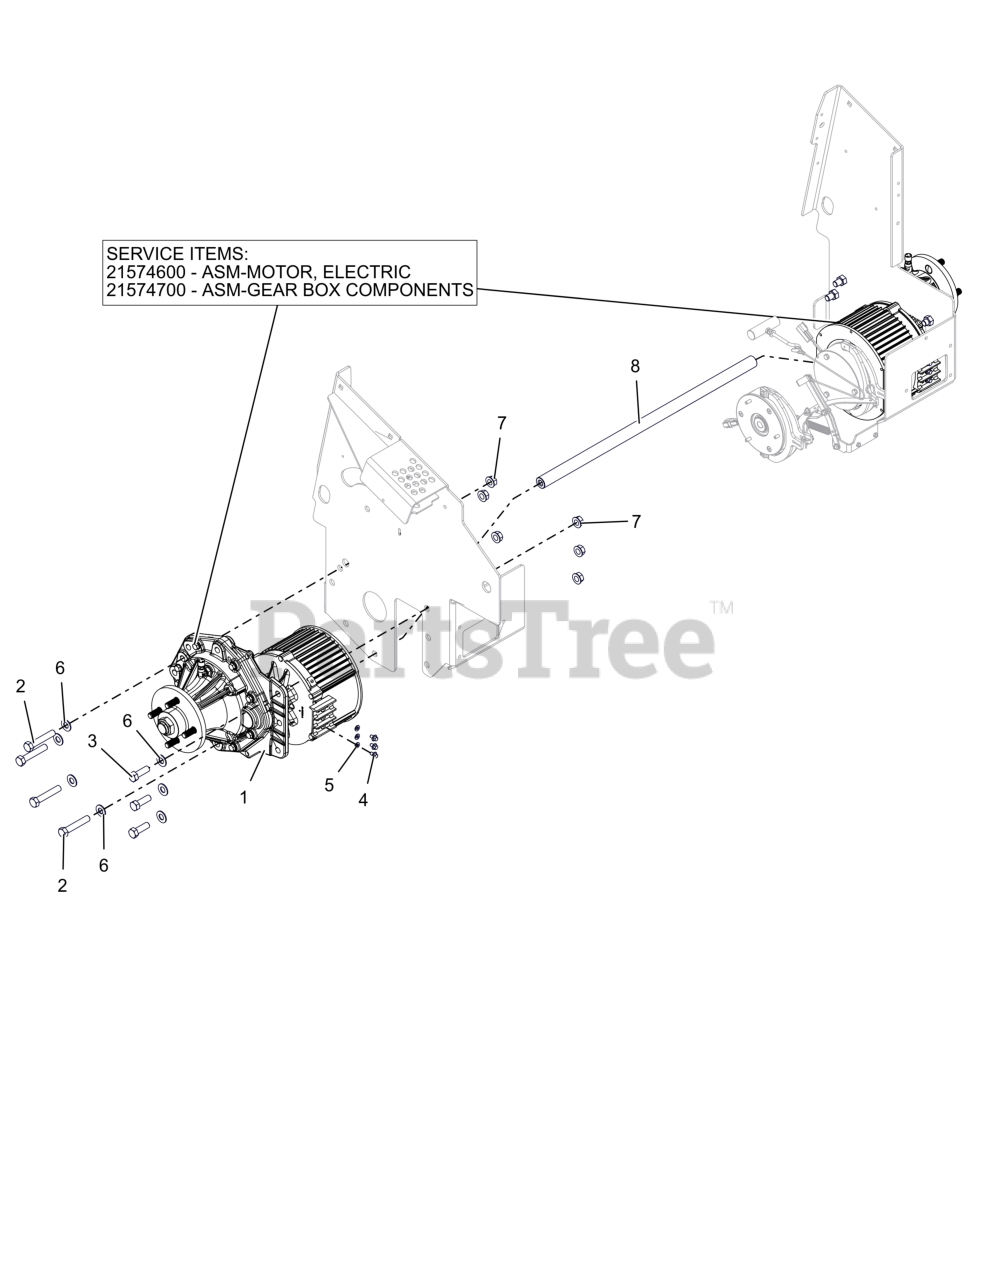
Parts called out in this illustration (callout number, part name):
1	ASM, WHEEL DRIVE
1	ASM-MOTOR, ELECTRIC
1	ASM-GEAR BOX COMPONENTS
2	BLT, HEX .50-13X2.75 G8 ZCC
3	BLT, HEX 0.5-13X1.5 GR8 ZCC
4	BLT,HEX M6-1X10 G8.8 ZCC
5	WSHR,LK-REG .250X.062 ZCC
6	WSHR, FLT .557X1.040X.102 ZCC
7	NUT, FLG-CTR LK .500-13 GG ZCC
8	SHAFT- TRANSAXLE SUPPORT
